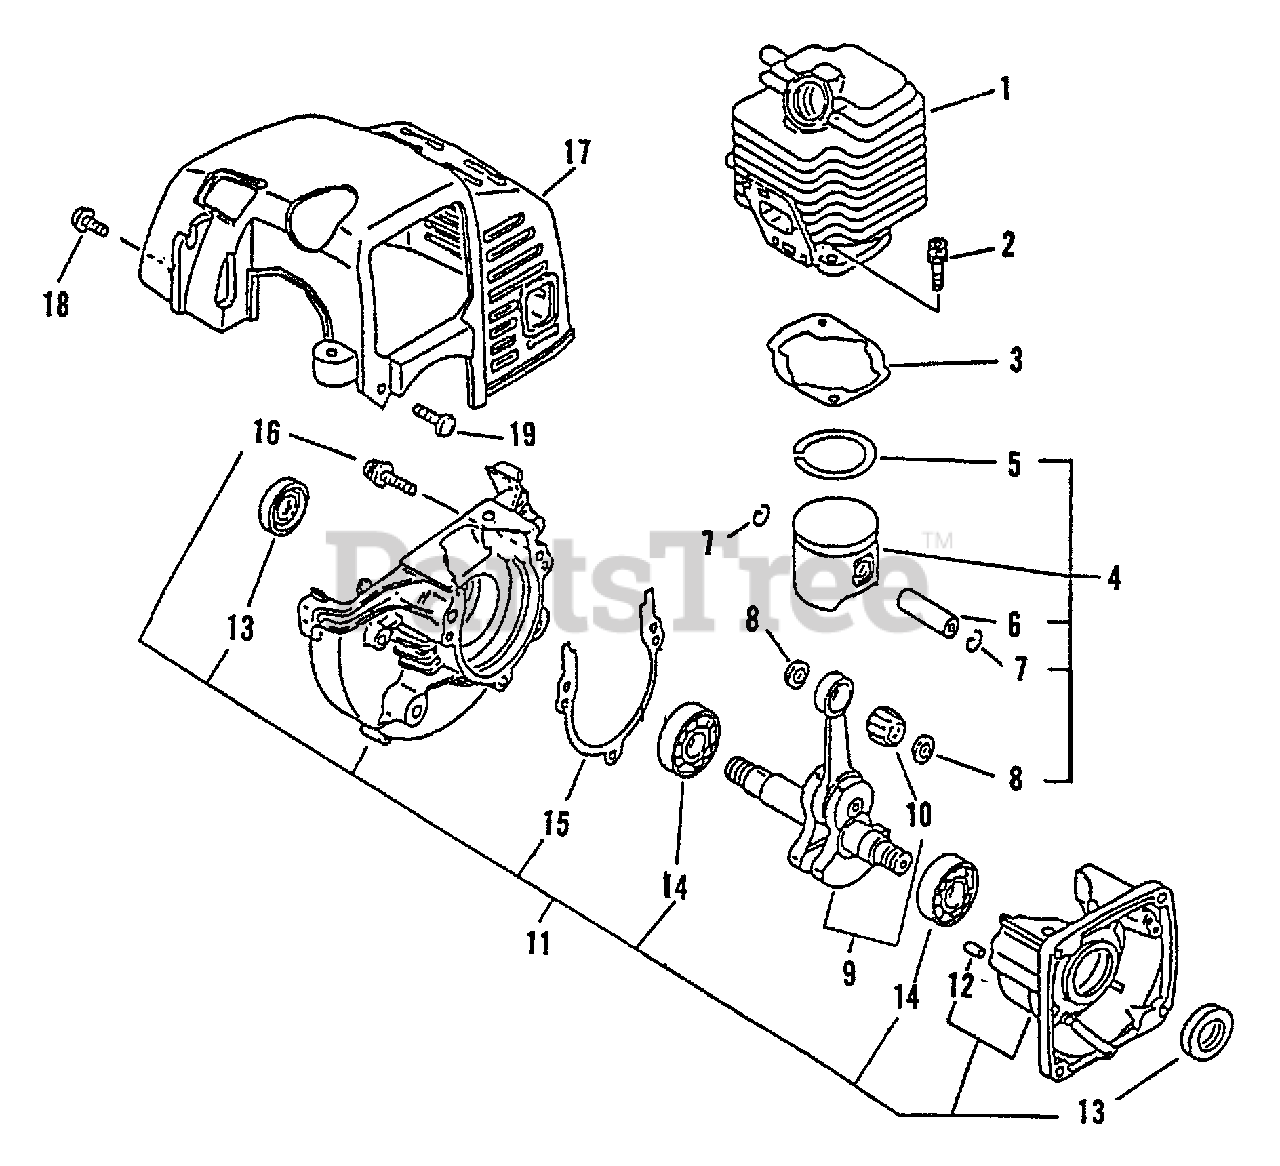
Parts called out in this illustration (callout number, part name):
1	CYLINDER
2	BOLT 5×22
3	GASKET, CYLINDER
4	PISTON KIT
5	RING, PISTON
6	PIN, PISTON 8
7	RING, SNAP
8	WASHER, THRUST
9	CRANKSHAFT ASSY
10	BEARING, NEEDLE
11	CRANKCASE KIT
12	PIN, LOCATING 4
13	SEAL, OIL 12
14	BEARING, BALL - 6201 C3
15	GASKET, CRANKCASE
16	BOLT 5×28
17	COVER, ENGINE
18	SCREW 4×14
19	SCREW 4×16
